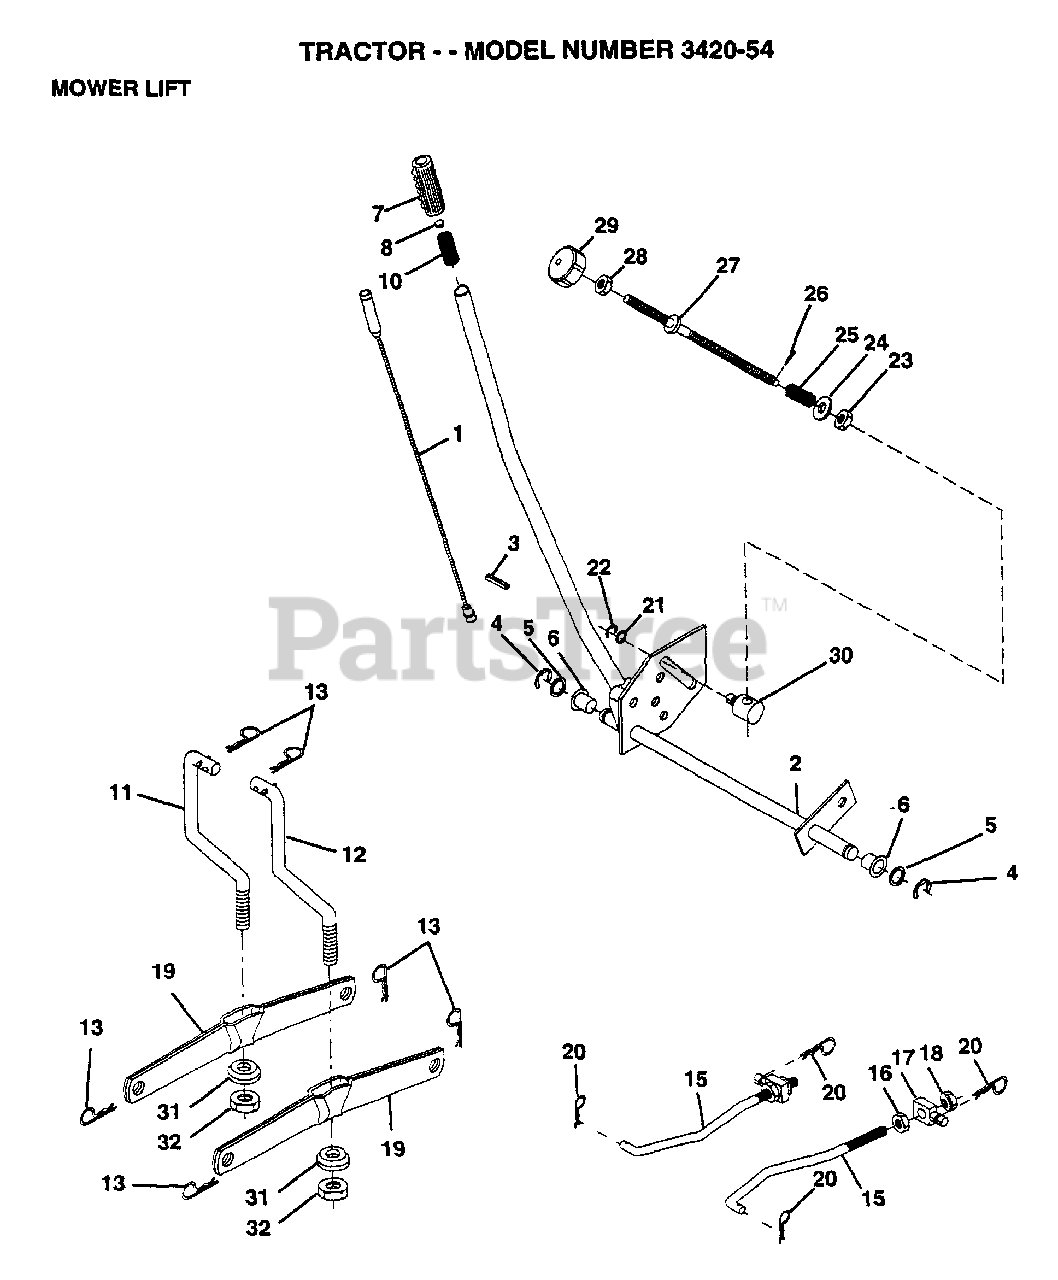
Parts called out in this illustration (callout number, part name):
1	WIRE ASM
2	SHAFT.ASM.LIFT LH
3	PIN GROOVE
5	WASHER
6	NYLON BEARING
7	GRIP
15	LINK.FRONT
16	NUT
17	TRUNION
18	NUT.LK.W/WSH.1/2.
19	ARM SUSP REAR
20	CLIP HAIRPIN
21	WASHER
22	KLIP RING
23	NUT T
24	WASHER
25	SPRING.COMP.INF.H
27	ROD.ADJ.LIFT
28	NUT
29	KNOB INF 3/8-16
30	TRUNION LT
31	BEARING PVT LH
32	NUT.CROWNLOCK.3/8
